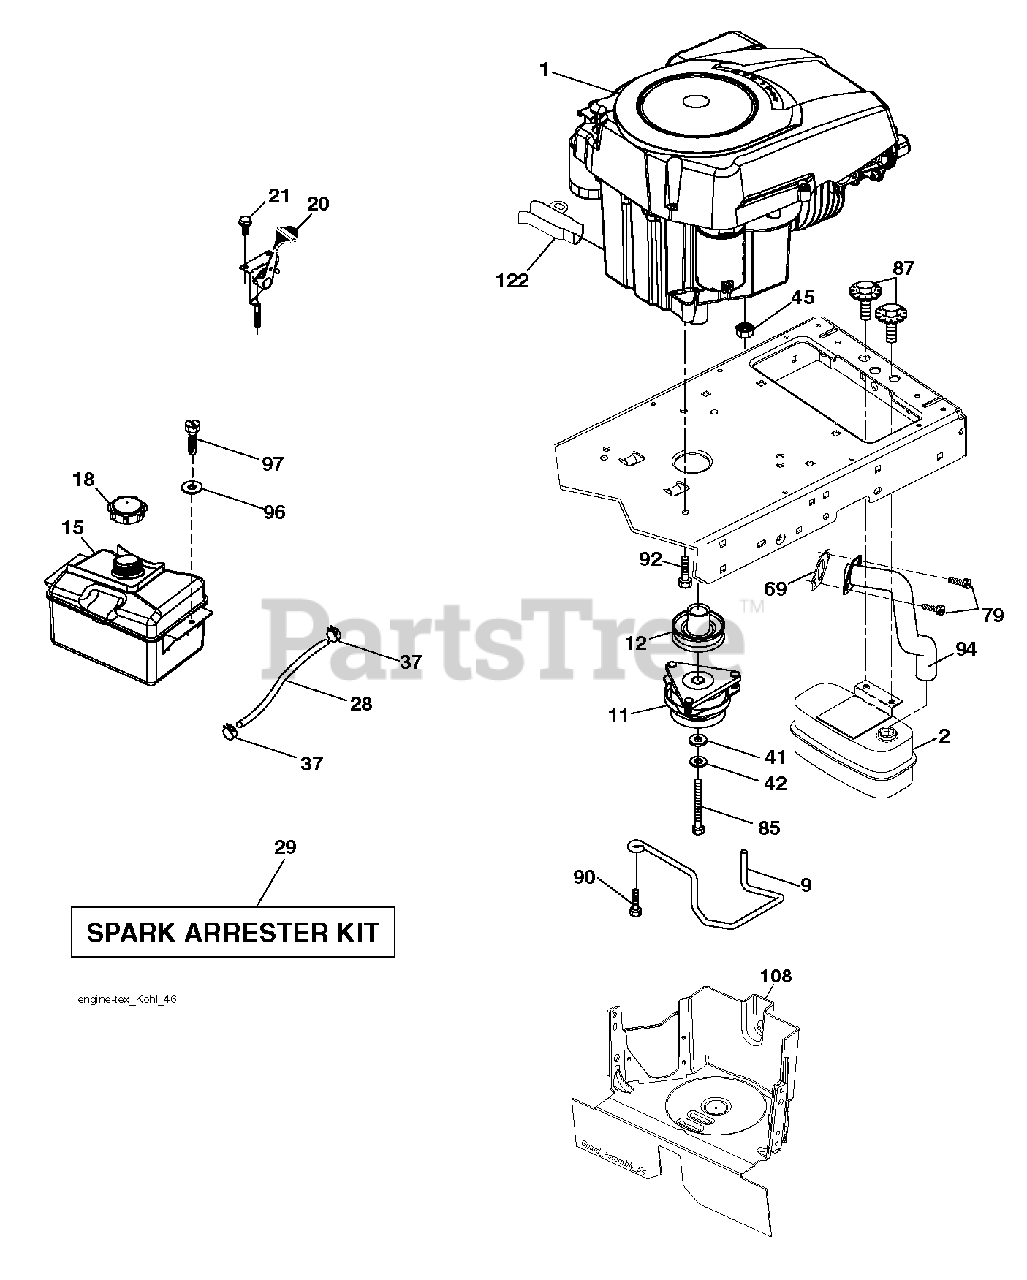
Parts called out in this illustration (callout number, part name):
2	MUFFLER.SINGLE.CYL.KOHL/B&S
9	KEEPER.BELT.ENGINE.4.2
11	CLUTCH.ELECTRIC.LT.48"*
12	PULLEY.ENGINE.TUFFTORQ
15	RP TANK FUEL FRT 1.5 GAL
18	CAP ASM.FUEL.2.25"FR.
20	CONTROL.TH/CK.C.
21	SCREW.#10 X 0.750.BOS
28	LINE.FUEL.20
29	KIT.SPARK ARRESTOR 794945 B&S
37	HOSE CLAMP
42	LOCKWASHER
45	NUT
69	GASKET.EXHAUST.KOHLER
79	SCREW.SOCKET HD.5/16-1
85	BOLT HEX 7/16-20X4-1/4"
87	BOLT, 5/16-18 X 1 3/4
90	SCREW 3/8-16X1
92	SCREW 3/8-16X1
94	RP.TUBE.EXHAUST.KOHL.COURAGE
97	SCREW HEXWSHR 1/4-20X3/4
108	COVER PULLEY
122	EXTENSION DRAIN OIL
